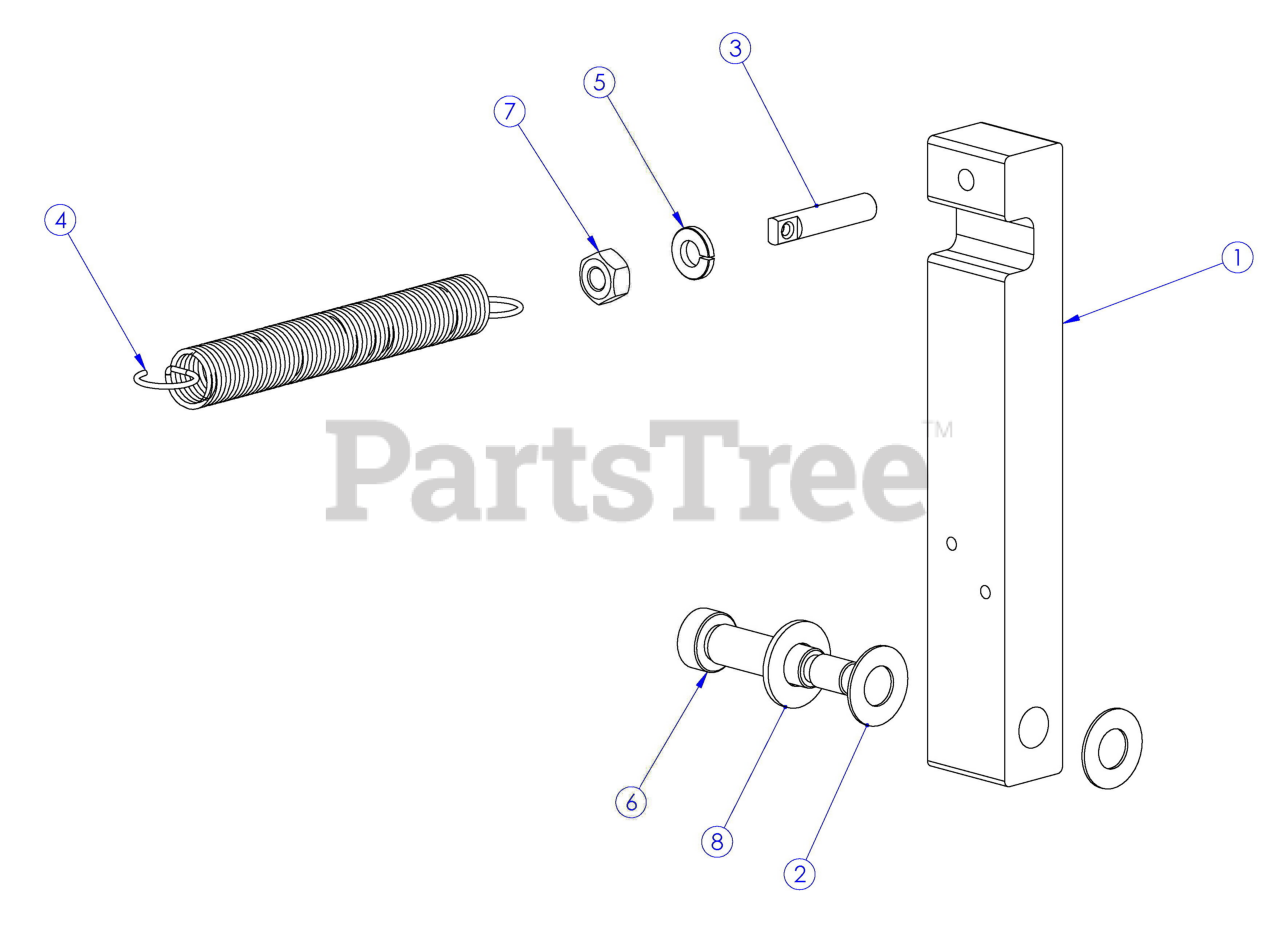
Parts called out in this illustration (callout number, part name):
1	Arm, Depth Gauge
2	Washer, 3/8" Delrin
3	Spring Anchor, 1/4-20 X 1
4	Spring, Extension
5	Washer, Split 1/4" S.S.
6	Shsb, 3/8 X 1 1/4
7	Nut, 1/4-20 Hex, S.S.
8	Washer, 3/8" Flat
